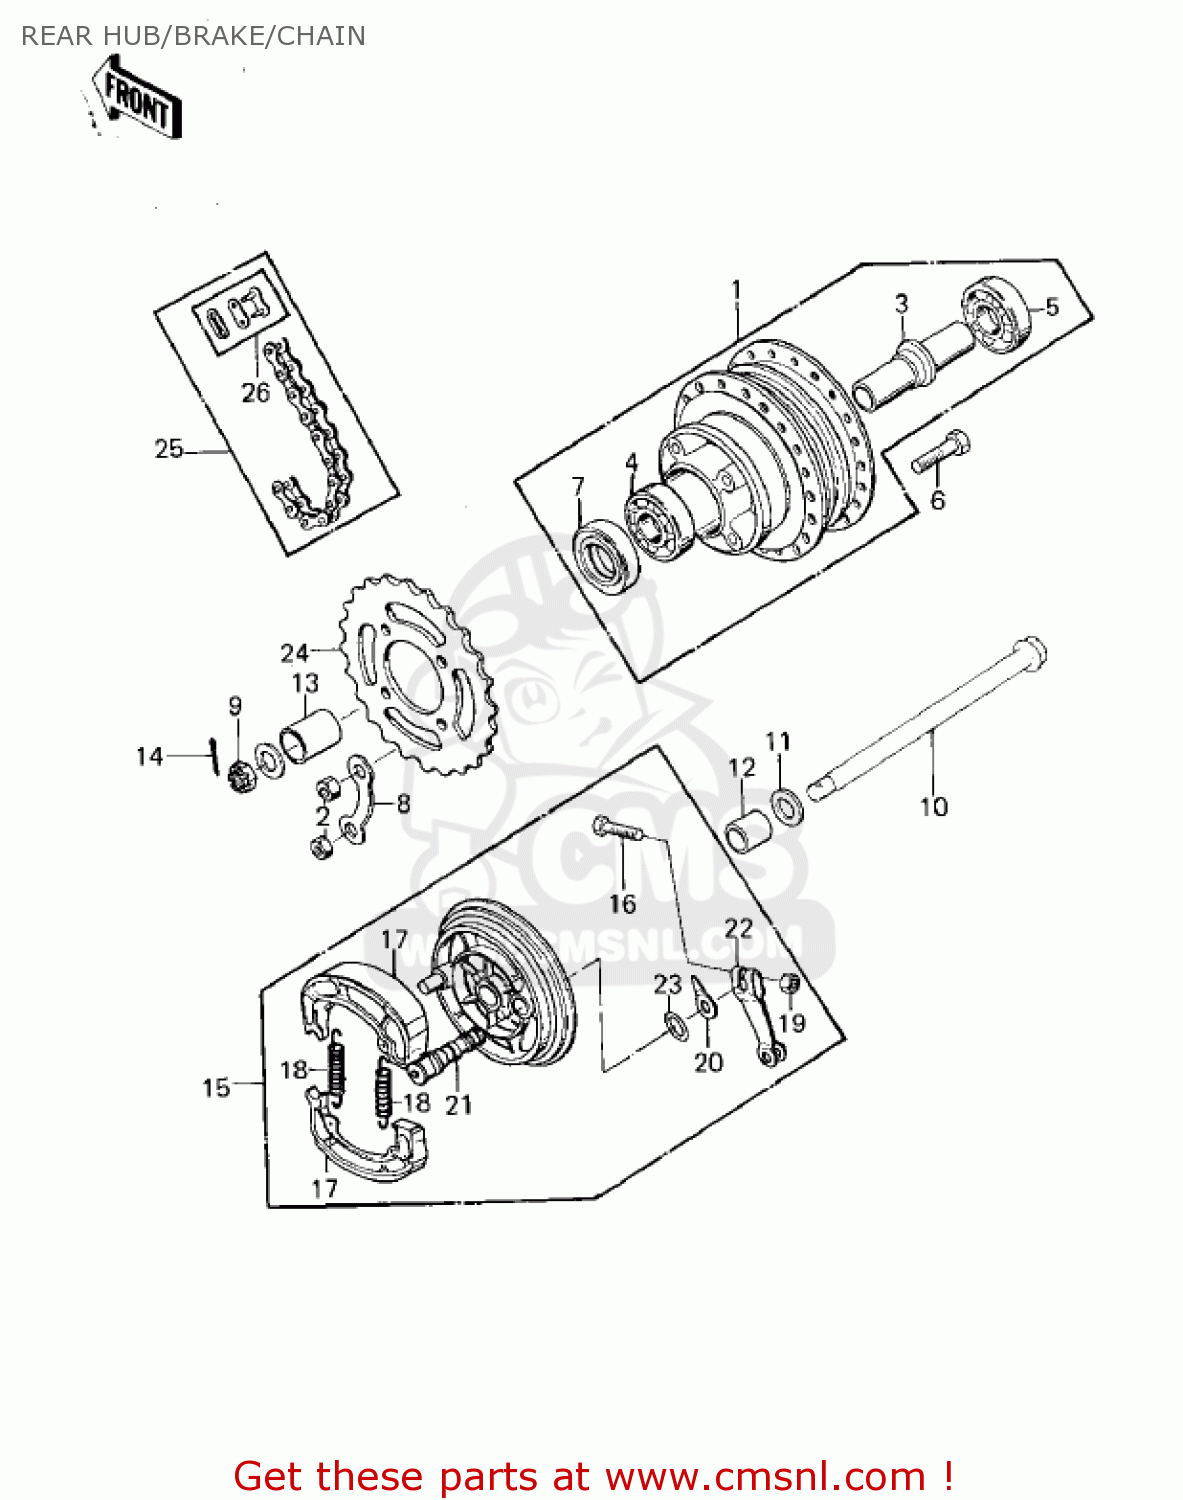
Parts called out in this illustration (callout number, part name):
1	DRUM ASSY,RR BRK,BUFF
2	NUT,8MM
3	COLLAR,L=85
4	BEARING-BALL,#6301C3
5	BEARING-BALL,#6301ZC3
6	BOLT-REAR SPROCKET
7	OIL SEAL-RR BRK DRUM
8	WASHER,SPROCKET LOCK
9	NUT-CASTLE
10	AXLE,12X206
11	WASHER-PLAIN,12MM
12	COLLAR,12.2X22X30.5
13	COLLAR,L=14
14	PIN-COTTER,3.0X25
15	PANEL ASSY,REAR BRAKE
16	BOLT-UPSET
17	SHOE-BRAKE (NAS)
18	SPRING,BRAKE SHOE
19	NUT,6MM
20	INDICATOR,BRAKE SHOE
21	CAM-BRAKE
22	LEVER-BRAKE CAM
23	RING-O,BRAKE CAM
24	REAR SPROCKET 39T
25	DRIVE CHAIN,EK428 98L
26	JOINT-CHAIN,EK428-G
